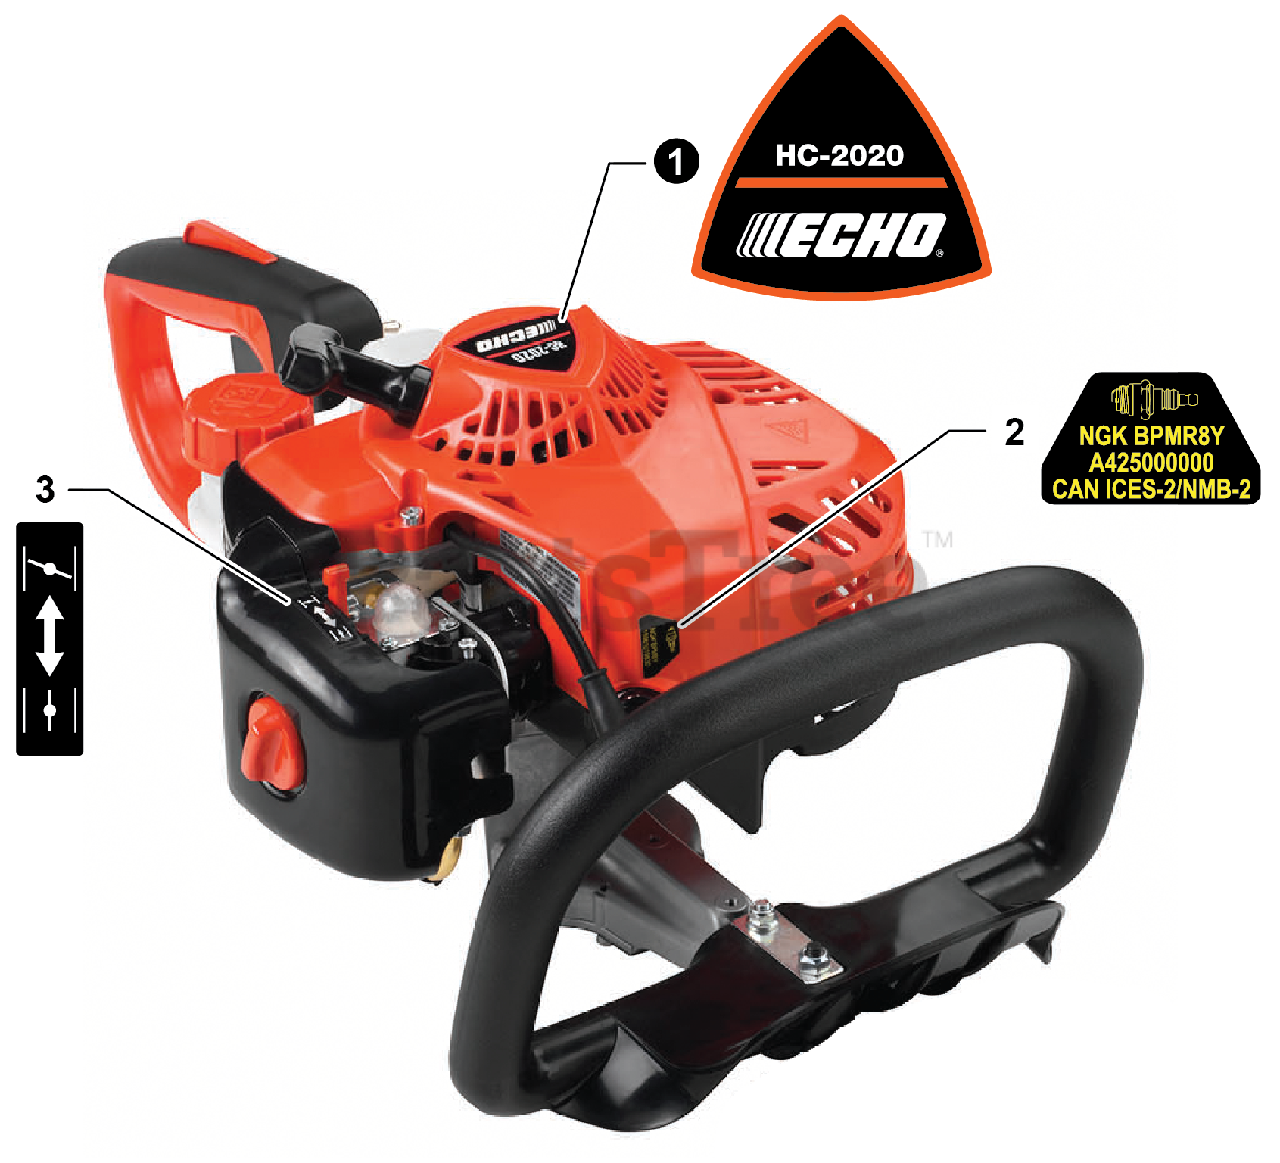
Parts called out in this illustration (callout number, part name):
1	LABEL - MODEL - HC-2020
2	LABEL - SPARK PLUG - BPMR8Y
3	LABEL - CHOKE
